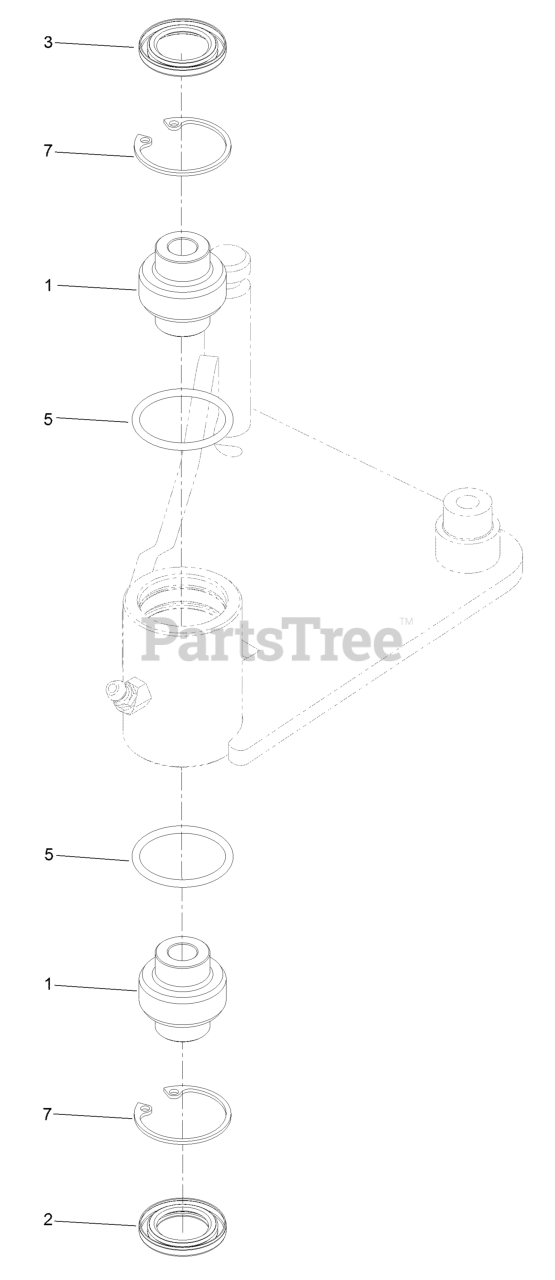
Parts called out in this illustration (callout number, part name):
1	Bearing-Spherical
2	Seal-Lip, Double
3	Seal-Lip, Single
7	Ring-Snap
